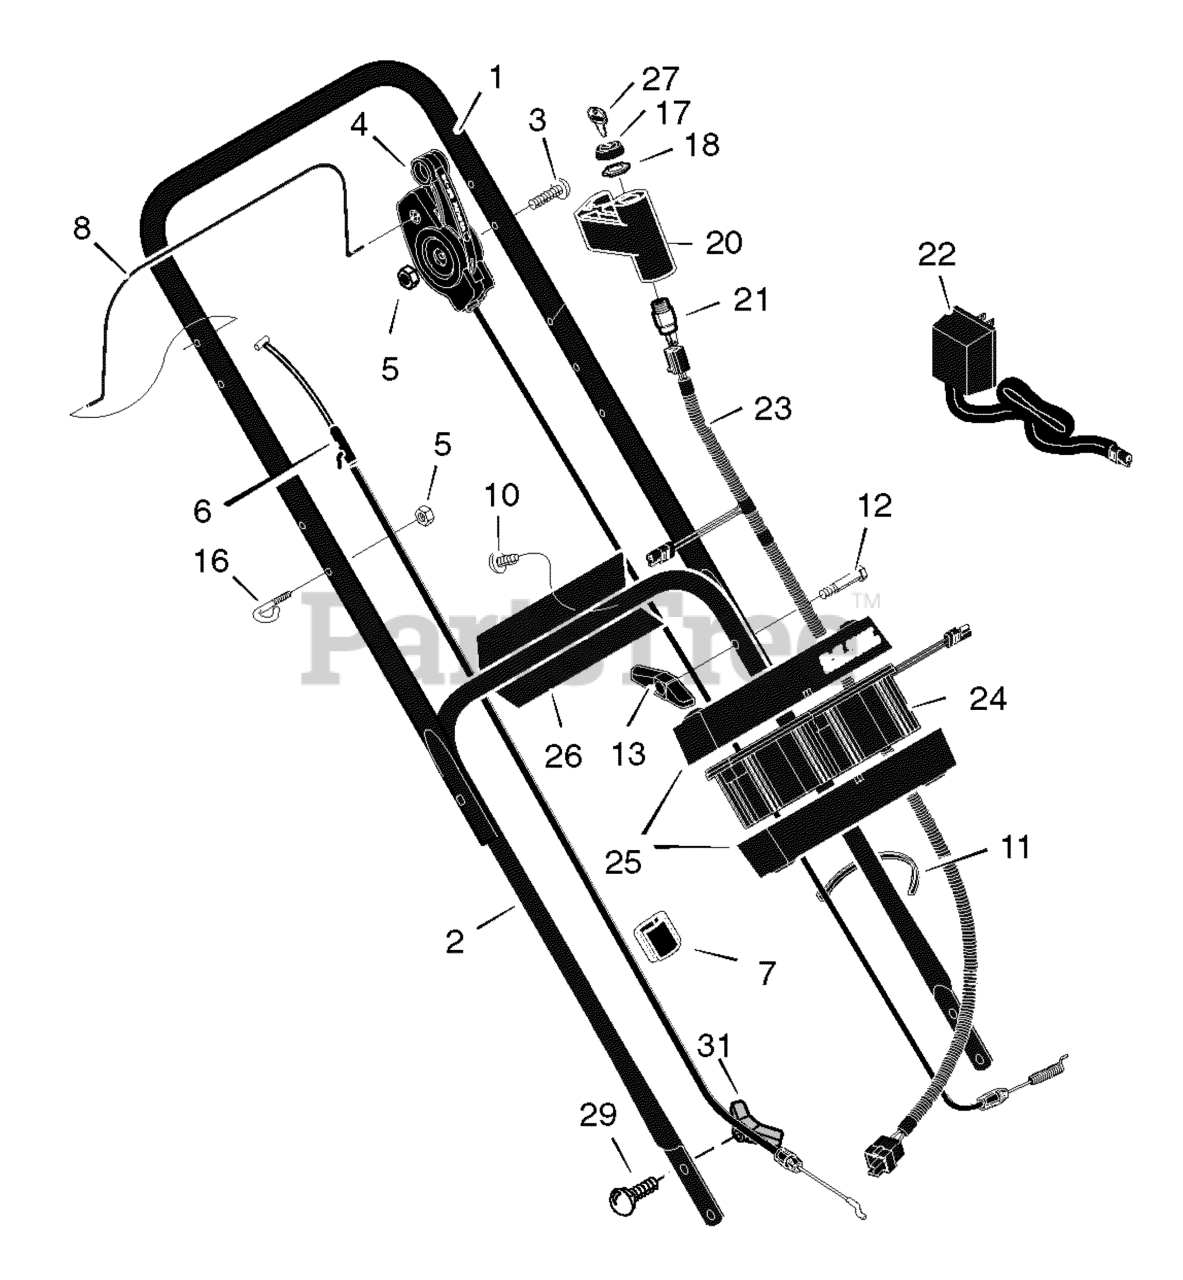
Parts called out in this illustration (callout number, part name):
1	Handle, Upper (Black)
1	Handle, Upper (Gray)
2	Handle, Lower (Black)
2	Handle, Lower (Gray)
4	Control, Drive
5	Locknut
6	Cable, Stop (Briggs)
6	Cable, Stop (Tecumseh)
7	Fastener, Double Cable
8	Lever, Stop
11	Fastener, Cable
16	Guide, Rope
17	Cap
18	Nut
20	Cover, Ignition
21	Switch Ignition & Key
22	Charger, Battery
23	Harness, Wiring
24	Battery
25	Case, Battery
26	Bracket, Battery
27	Key, Ignition
29	Bolt, Carriage
31	Knob, Plastic
